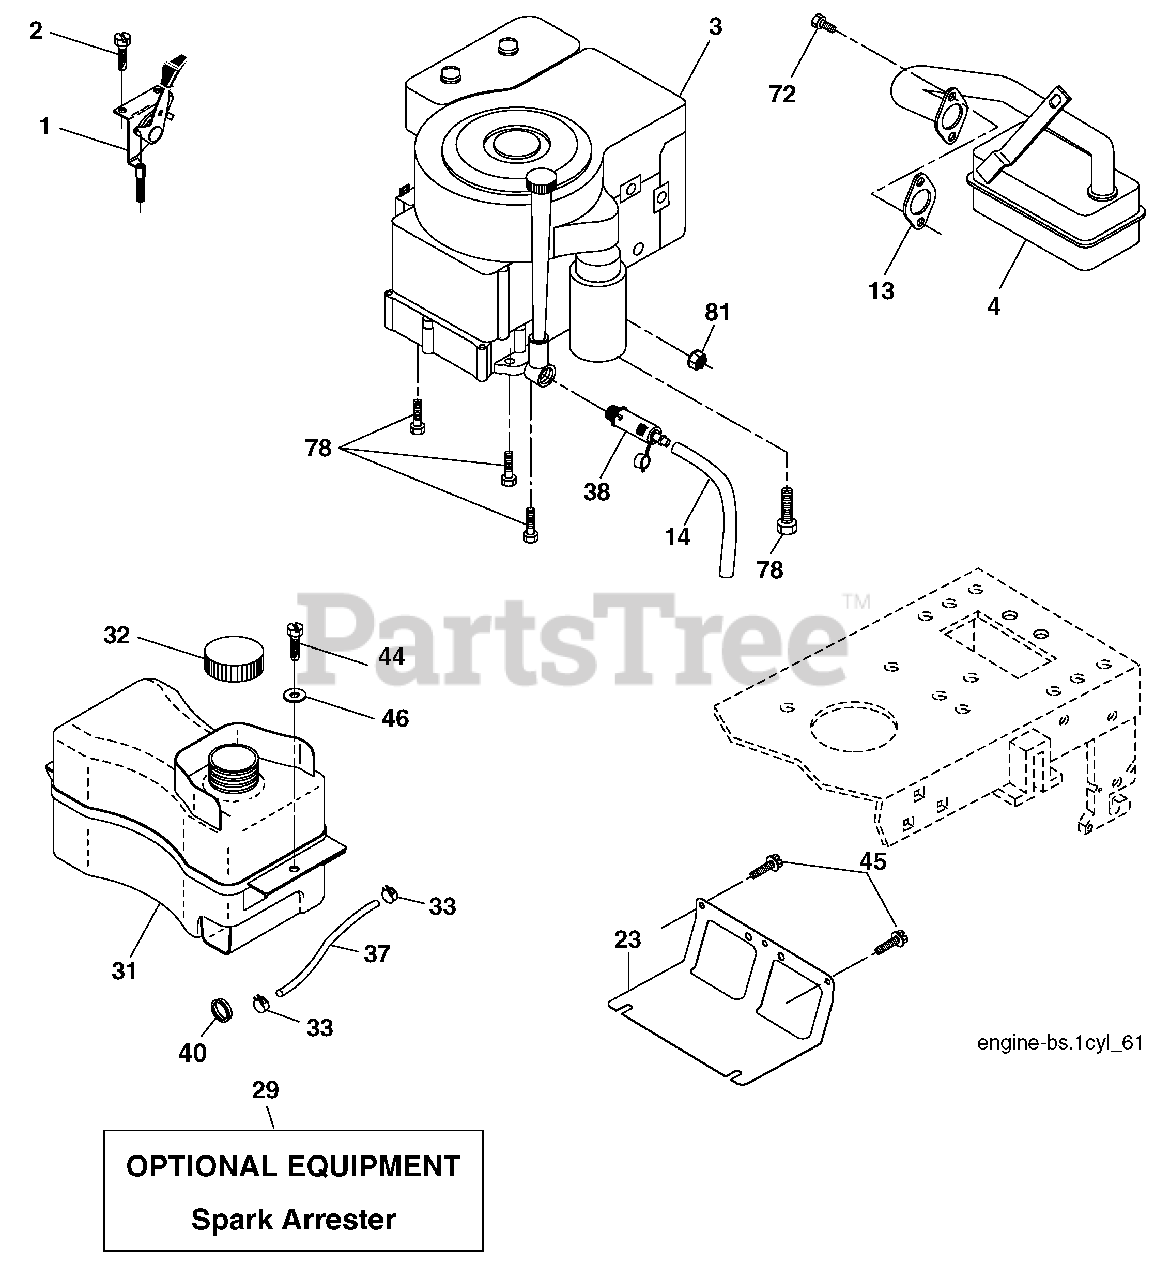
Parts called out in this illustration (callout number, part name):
1	Control Th/ch Flag
2	Screw Hex Thd Cut 1/4-20 x 1/2
4	Muffler Exhaust B&S
13	Gasket Eng 1 313 Id Tin Plated
14	Tube Drain Oil Easy
23	Shield BRN/DBR Guard
29	Kit Spark Arrestor (Flat Scrn)
31	Tank Fuel Front
32	Cap Asm Fuel
33	Clamp Hose
37	Line Fuel 20"
38	Plug Drain Oil
40	Bushing Snap Nyl Blk Fuel Line
44	Screw Thdrol 1/4-20 x 3/4
45	Screw Hex Wsh Thdrol 3/8-16
46	Washer 9/32 x 7/8 x 16 Ga.
72	Screw Socket Head 5/16-18 x 3/4
78	Screw 3/8-16 x 1-1/4
81	Nut Keps Hex 1/4-20 unc
